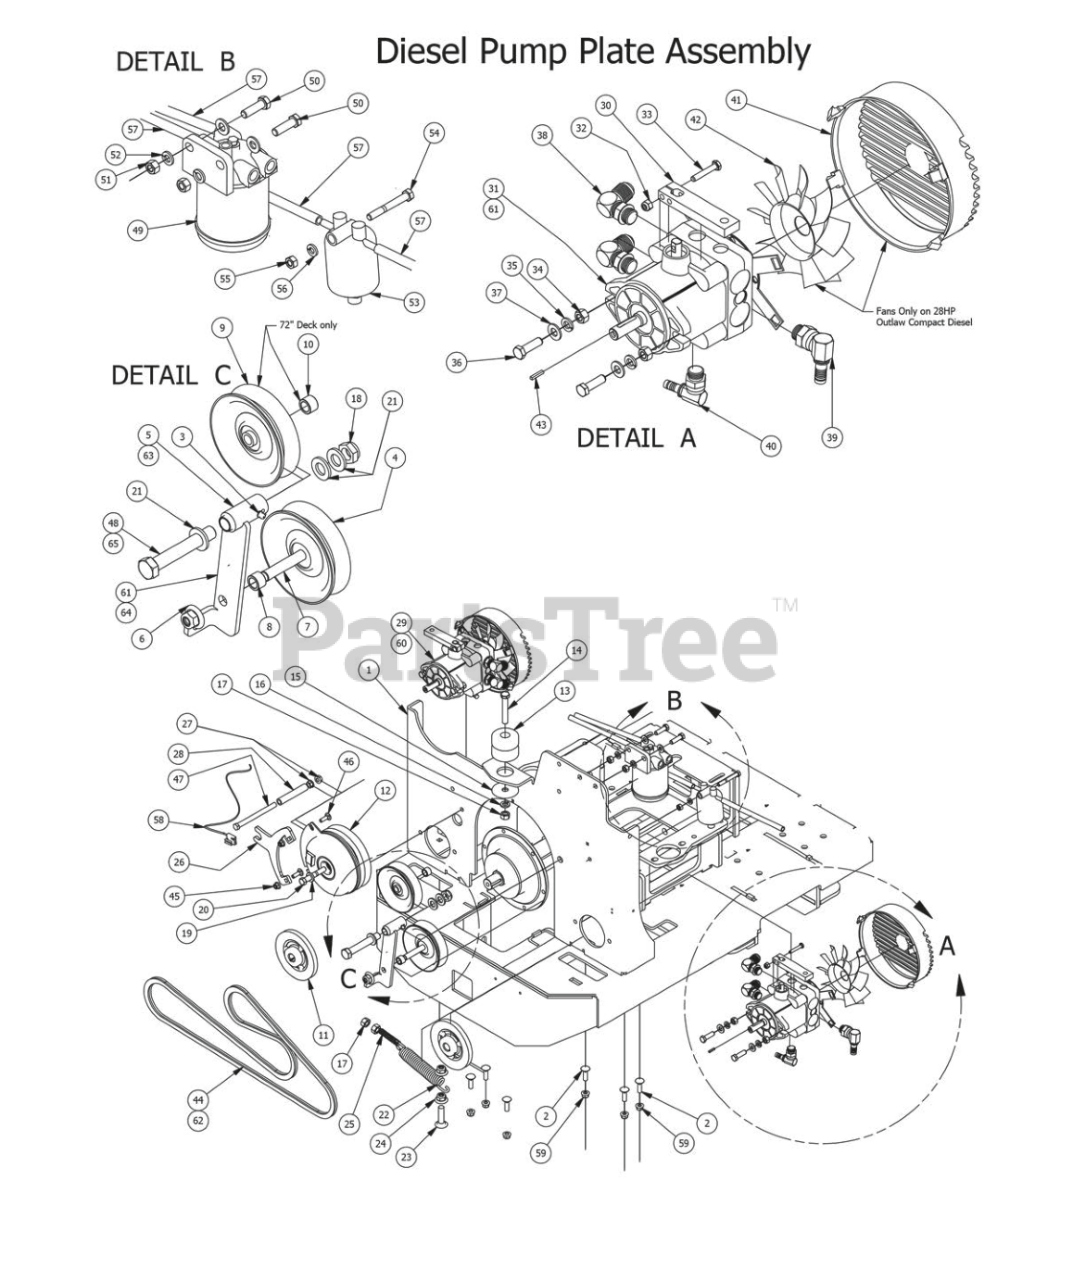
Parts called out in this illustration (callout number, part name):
1	Pump Plate Diesel
2	3/8" x 1 1/4" Carriage Bolt
3	1/4" Drive in Grease Fitting
4	43/4" Idler Pulley
5	Pump Idler Bracket only for 61" Deck
6	1/2-13 Nylon Flange Nut-Orange
7	1/2" x 3" Hex Bolt
8	1/2 x 1/2 Spacer
9	5" Idler Pulley only for 72" Deck Diesel
10	5/8" x 1/" Collar Spacer only for 72" Deck Diesel
11	5" Pump Pulley
12	Clutch Assembly for Diesel
13	Armor Plated Mount-Rear Mount
14	1/2" x 3" Hex Bolt
15	Snubbing Washer
16	1/2" Lock Washer
17	1/2" Hex Nut
18	5/8" Nylock (1/2 Jam)
19	7/16" Lock Washer
20	7/16" x 2 3/4" Fine Thread Bolt
21	.630 ID x 1.122 OD x .142 THK Plastic Washer
22	Deck Idler Spring
23	1/2 x 2" Carriage Bolt
24	1/2-13 Nylon Flange Nut-Orange
25	1/2-13 x 2-1/2 All Thd Stud
26	Diesel PTO Engager Holder
27	3/8" Flange Nut
28	3/8 hose 4" long
29	PR Pump W/Fan Left -28Hp Diesel
31	PR Pump with Fan and Cover Right - 28Hp Diesel
32	1/4" Nylock Nut
33	1/4" x 1 1/2" Bolt
34	3/8" Hex Nut
35	3/8" Lock Washer
36	3/8" x 1 1/2" Hex Bolt
37	3/8" Flat Washer
38	6801-LL-8-8 Fitting - Compact Diesel
39	90 Degree Fitting 1/2" x 3/4" 4601-8-8
40	90 Degree Fitting 3/8" X 9/16"-4601-6-6
41	Fan Guard 7" Fits Compact Diesel Only
42	Hydro Fan Diesel 28hp Only
43	5mm x 1.25" Key
44	Pump Belt 28Hp Diesel
45	5/16" Flange Nut
46	5/16" x 1" Carriage Bolt
47	3/8-16 x 5 Hex Bolt - Grade 5
48	5/8" x 4" Hex Bolt 61" Deck only
49	Fuel Filter
50	3/8" x 1 1/4" Hex Bolt
51	3/8" Hex Nut
52	3/8" Lock Washer
53	Caterpillar Fuel Bowl Kit
54	5/16" x 2 1/2" Bolt
56	5/16" Lock Washer
57	5/16" fuel line hose
58	Clutch Pigtail
59	3/8" Nylock Flange Nut
60	Left Pump 16cc - AOS Diesel 35Hp Diesel
61	Right Pump 16cc - AOS Diesel 35Hp Diesel
62	Pump belt for 35HP Diesel
63	Diesel Pump Idler only on 72" Deck
64	Diesel Pump Idler Assembly Components 3,4,5,6,7,8,9,10 only for 72" Deck
65	5/8 x 5 1/2 Bolt only for 72" Deck
